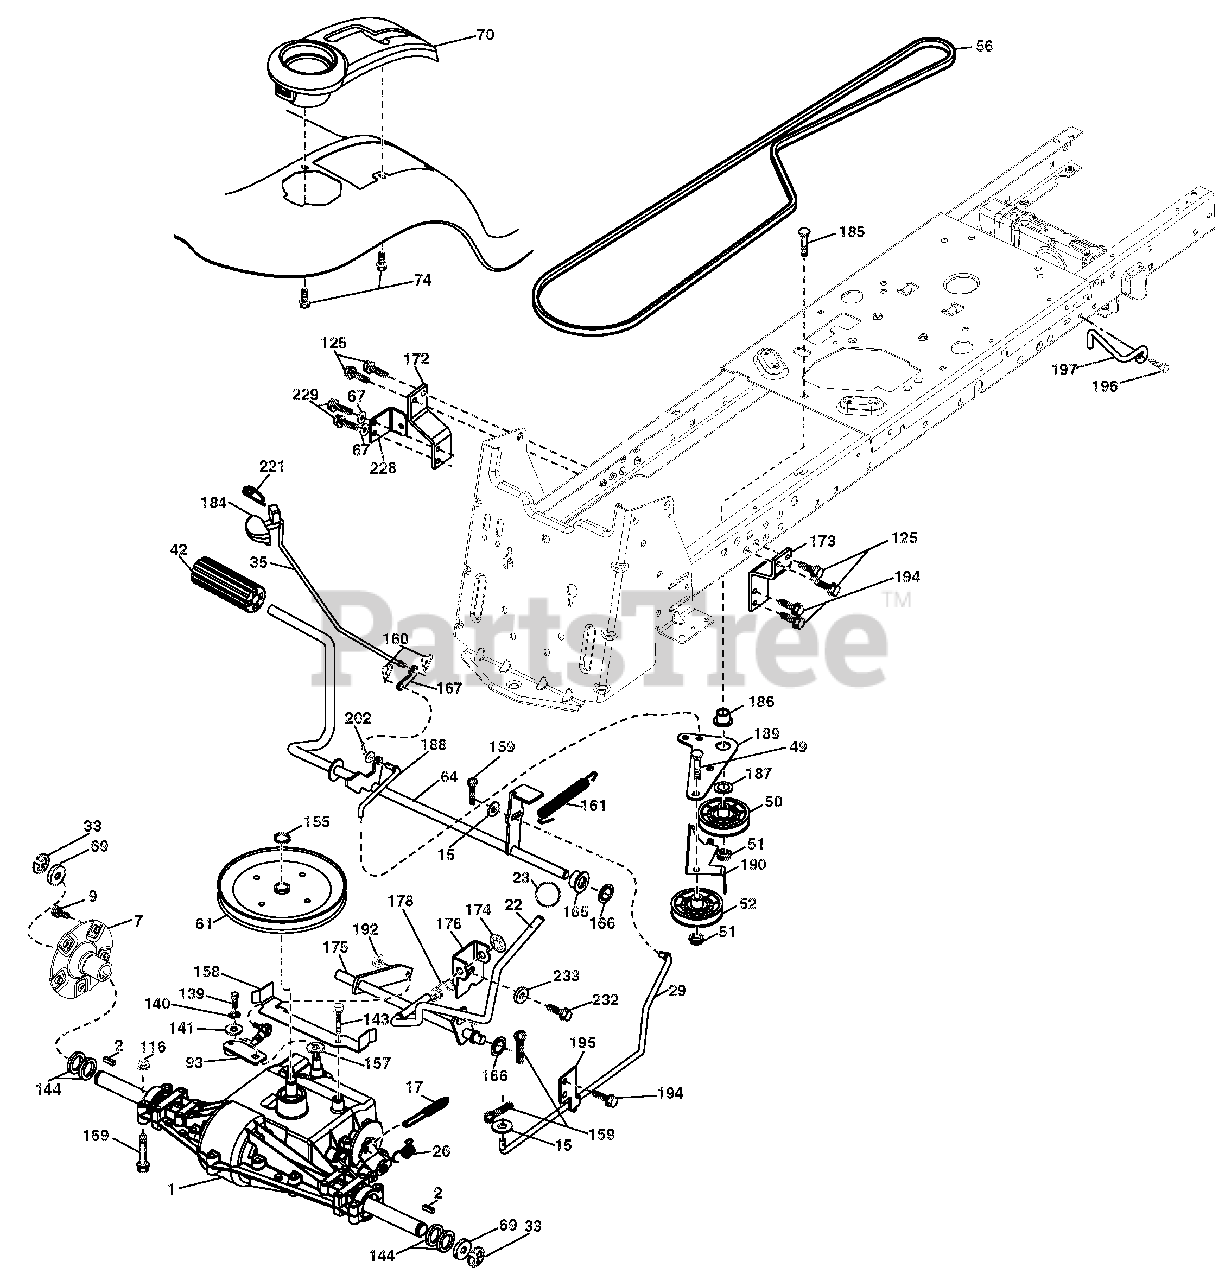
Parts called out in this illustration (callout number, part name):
1	TRANSAXLE, PEERLESS P820-040 (197458) (ORDER PARTS FROM TRANSAXLE MANUFACTURER.)
2	KEY 1/4 X 2.5
7	HUB ASM. WHEEL
9	BOLT HUB WHEEL
15	WASHER.13/32 X 13/16 X 16 GA.
17	SPRING.BRAKE.PEERLESS/D6800.TX
22	SHIFT SHAFT ASM.
23	KNOB DELUXE
26	SPRING.BRAKE.RTN.GR DR.TEX.006
29	ROD.BRAKE.PEERLESS/D6800
35	ROD BRAKE PARKING LT TEX
42	COVER PEDAL BLK ROUND
49	BOLT.RDHD.3/8-16UNCX1-3/4.GR5
50	IDLER.FLAT.910"OFFSET
51	Nut, Hex, Flangelock 3/8-16
52	IDLER.V-GROOVE.910"OFFSET
56	V-BELT, DRIVE
61	PULLEY TRANSAXLE
64	SHAFT ASM.PEDAL.BRAKE CONTROL
67	Washer 13/32 x 13/16 x 12 Ga.
69	WASHER 1-1/32 X 1-5/8 X 16 GA.
70	CONSOLE
74	SCREW.HEX.WSH.HI-LO.1/4X1/2UNC
93	LINK SHIFT
116	Nut, Lock Hex Flange 5/16-18 u
125	SCREW.5/16-18X3/4.SMGML.TAP/BL
139	BOLT.1/4-28 UNF.GR8.W/PATCH
140	Washer, Lock 1/4
141	WASHER.9/32 X 3/4 X 10 GA.
143	SCREW.THDROL.5/16-18 X 1/2TYTT
144	WASHER SPACER AXLE
155	RING RETAINER
157	WASHER.PLATE.SHF..388 SQ.HOLE
158	BELT KEEPTER
159	PIN.COTTER.1/8 X 3/4.CAD.
160	RETAINER.CLIP(M).DIA.290
161	SPRING.RETURN.CLUTCH.6.75
165	BUSHING.SHAFT.BRAKE.HAND CONTR
166	NUT PUSH .625
167	LATCH.BRAKE.PARKING
169	BOLT 5/16-18 X 2 1/2 G.5
172	STRAP TORQUE LH
173	TORQUE STRAP RH
174	NUT.PUSH..500
175	SHAFT ASM. SHIFT GEAR DRIVE
176	ARM.CLEVIS.ROD.SHIFT
178	SPRING.SHIFT.GT.2006
184	HANDLE.PARKING BRAKE.
185	BOLT.RDHD.3/8-16UNC X2-3/4 GR5
186	SPACER.RETAINER
187	WASHER.13/32 X 2 X 10 GA.
188	LINK.CLUTCH.GROUND DRIVE
189	BELLCRANK.GROUNDRIVE.NSTG/NSTL
190	KEEPER.BELLCRANK.DRIVE.GROUND
192	NUT.LOCK.CENTER.1/4-28 FNTHD.
194	SCREW.5/16-18X3/4.SMGML.TAP/R
195	BRACKET.ROD.BRK.PEERLESS/D6800
196	SCREW.3/8-16X1.SMGML.TAP/R.BLK
197	BRACKET CLUTCH ANTI-ROTATION
202	Washer 11/32 x 11/16 x 16 Ga.
221	RETAINER.SPRING.CLIP.HANDLE
228	BRACKET ANTI-SWAY
229	SCREW 5/16-18 X 1
232	BOLT.FIN HEX.7/16-14X1 GR5
233	WASHER.SERRATED
